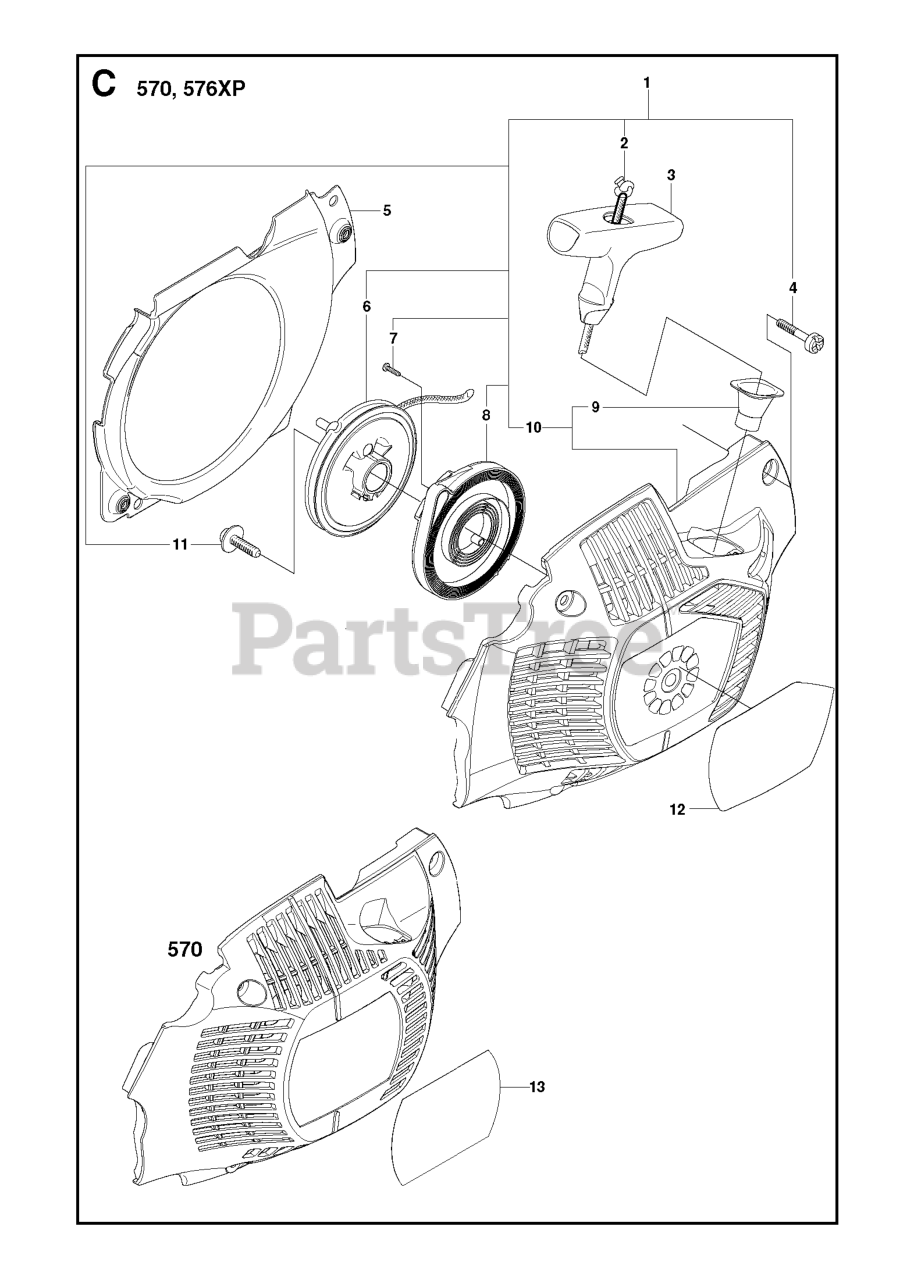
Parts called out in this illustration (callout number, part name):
1	STARTER ASSY
1	STARTER ASSY COMPLETE
2	STARTER ROPE
4	SCREW.CIHPANMO M5X19 10.9
6	STARTER PULLEY
8	RP SPRING
10	STARTER COVER
10	STARTER HOUSING
12	LABEL
13	DECAL
